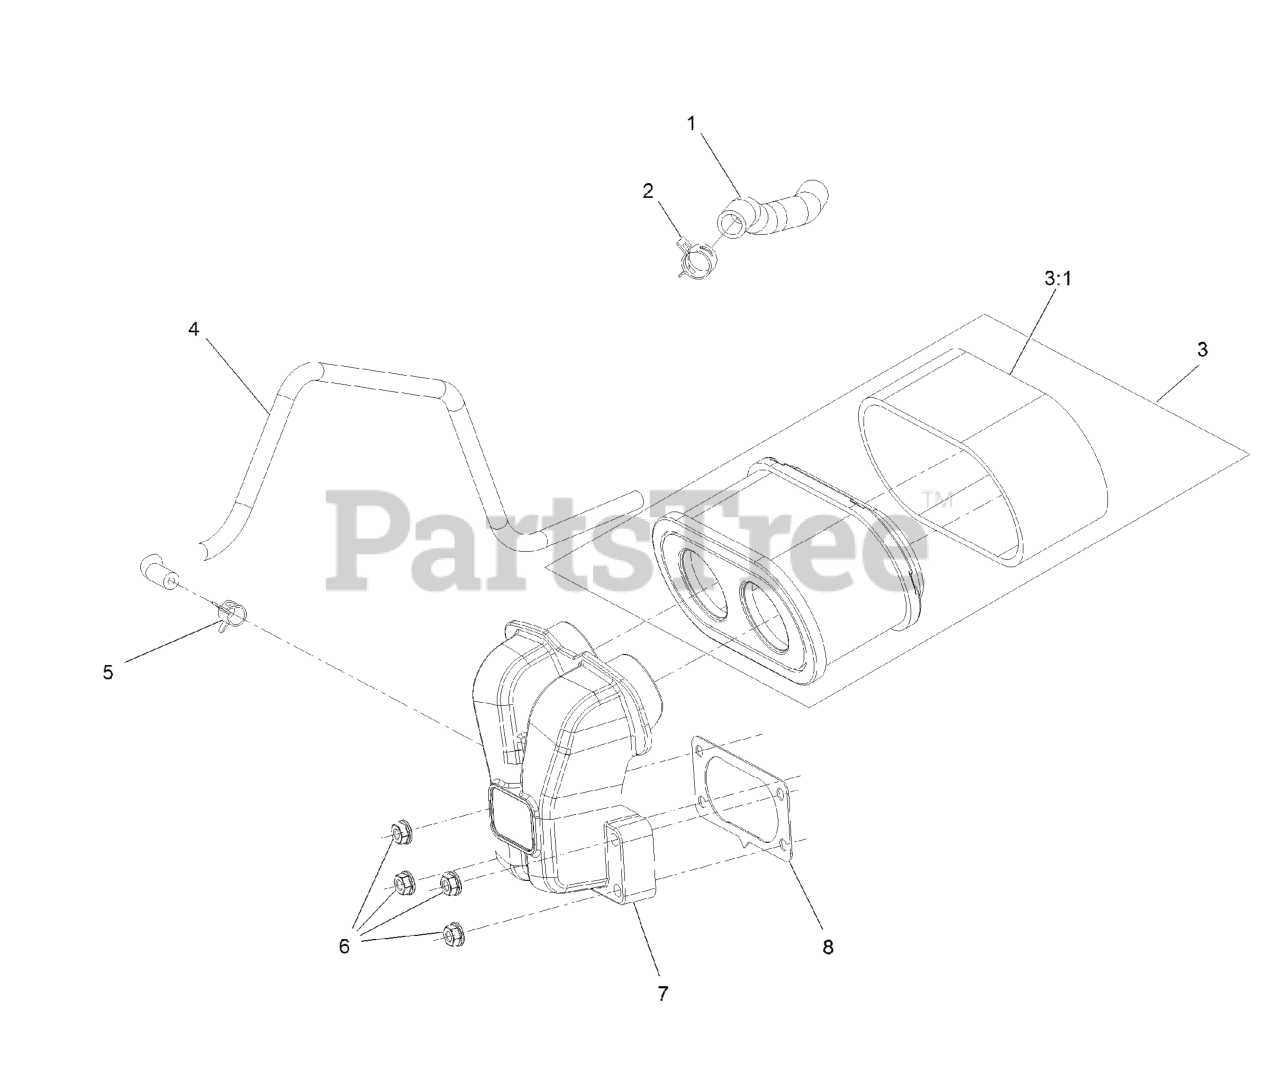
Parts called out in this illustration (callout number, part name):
1	TUBE-BREATHER
2	CLAMP-HOSE
3	AIR FILTER KIT
3:1	PREFILTER
4	HOSE-FUEL
5	CLAMP-HOSE
6	NUT-FLANGE
7	MANIFOLD-FILTER, AIR
8	GASKET-CARBURETOR
